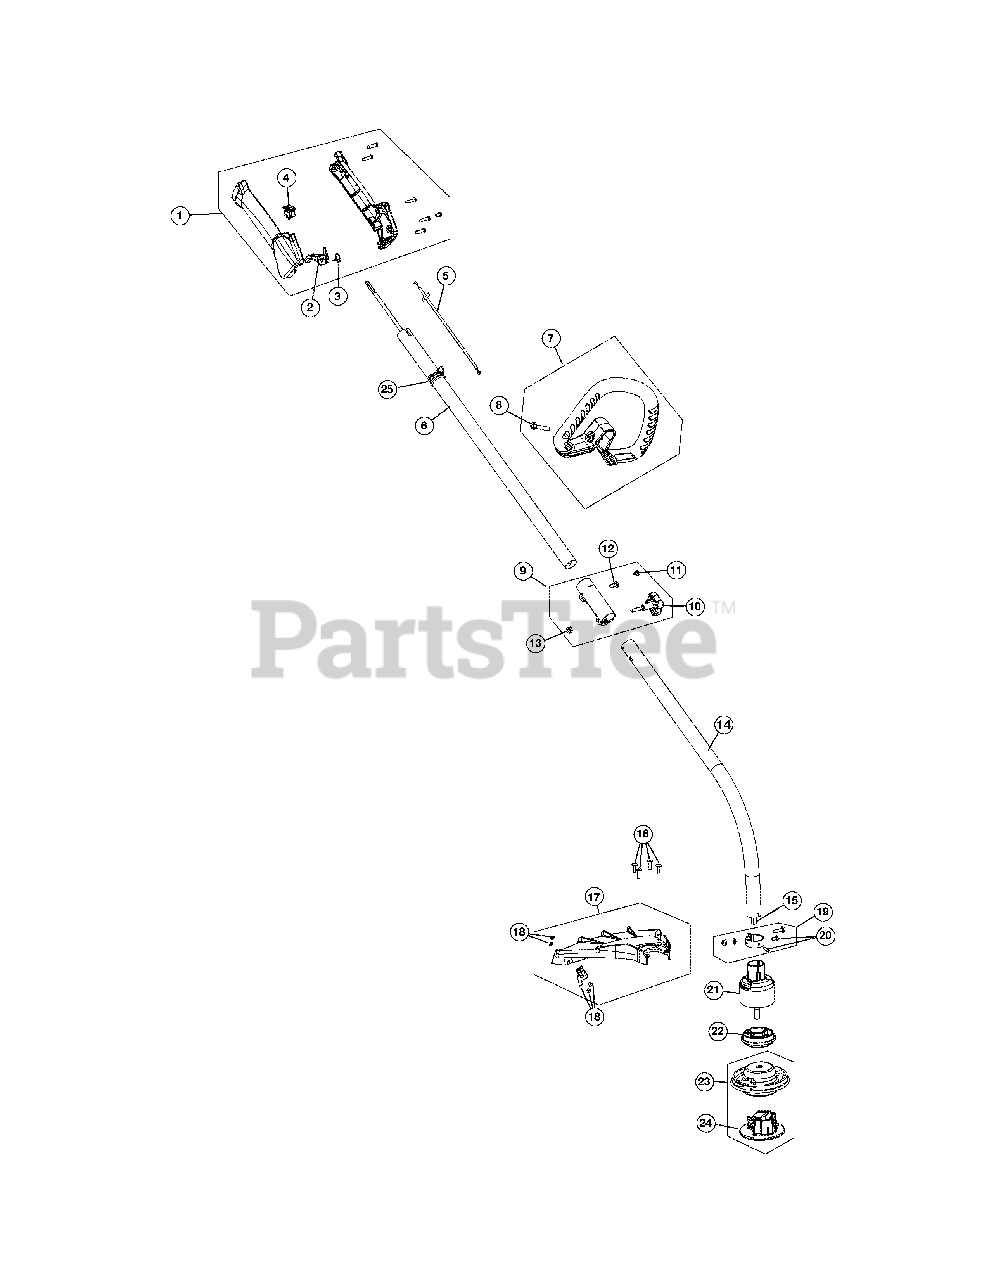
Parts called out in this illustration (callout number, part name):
1	Throttle Housing Assembly (Incl Ref No.2-4)
2	Throttle Trigger
3	Throttle Trigger Spring
4	Switch Assembly
5	Throttle Cable Assembly
6	Upper Drive Shaft Assembly
7	D-Handle Assembly (Incl Ref No.8)
8	Handle Hardware
9	Split Boom Coupler (Incl Ref No.10-13)
10	Adjustment Knob (Incl Ref No.13)
11	Coupler Anti-Rotation Screw
12	Coupler Bolt
13	Adjustment Knob Nut
14	Lower Drive Shaft Housing (Incl Ref No.15)
15	Lower Flexible Drive Shaft
16	Shield Mount Screw Assembly
17	Shield Assembly (Incl Ref No.18)
18	Blade Assembly
19	Lower Clamp Assembly (Incl Ref No.20)
20	Anti-Rotation Screw
21	Bushing Housing Assembly
22	Adapter
23	Cutting Head Assembly (Incl Ref No.24)
24	Cutting Head Cap
25	Shoulder Strap Clip
